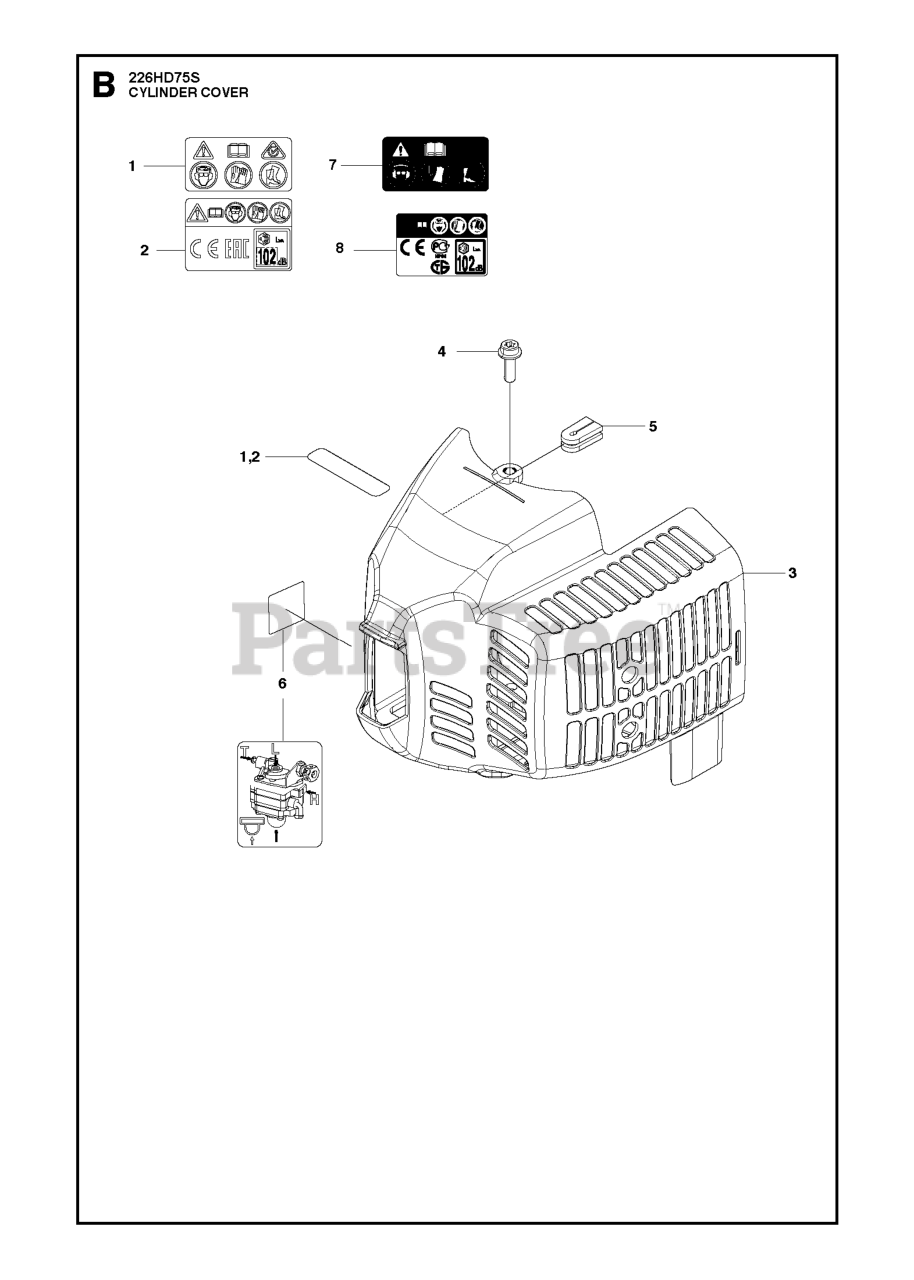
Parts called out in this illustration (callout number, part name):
1	DECAL
3	COVER ENGINE
6	DECAL ADJ LOCATION
7	LABEL WARNING
